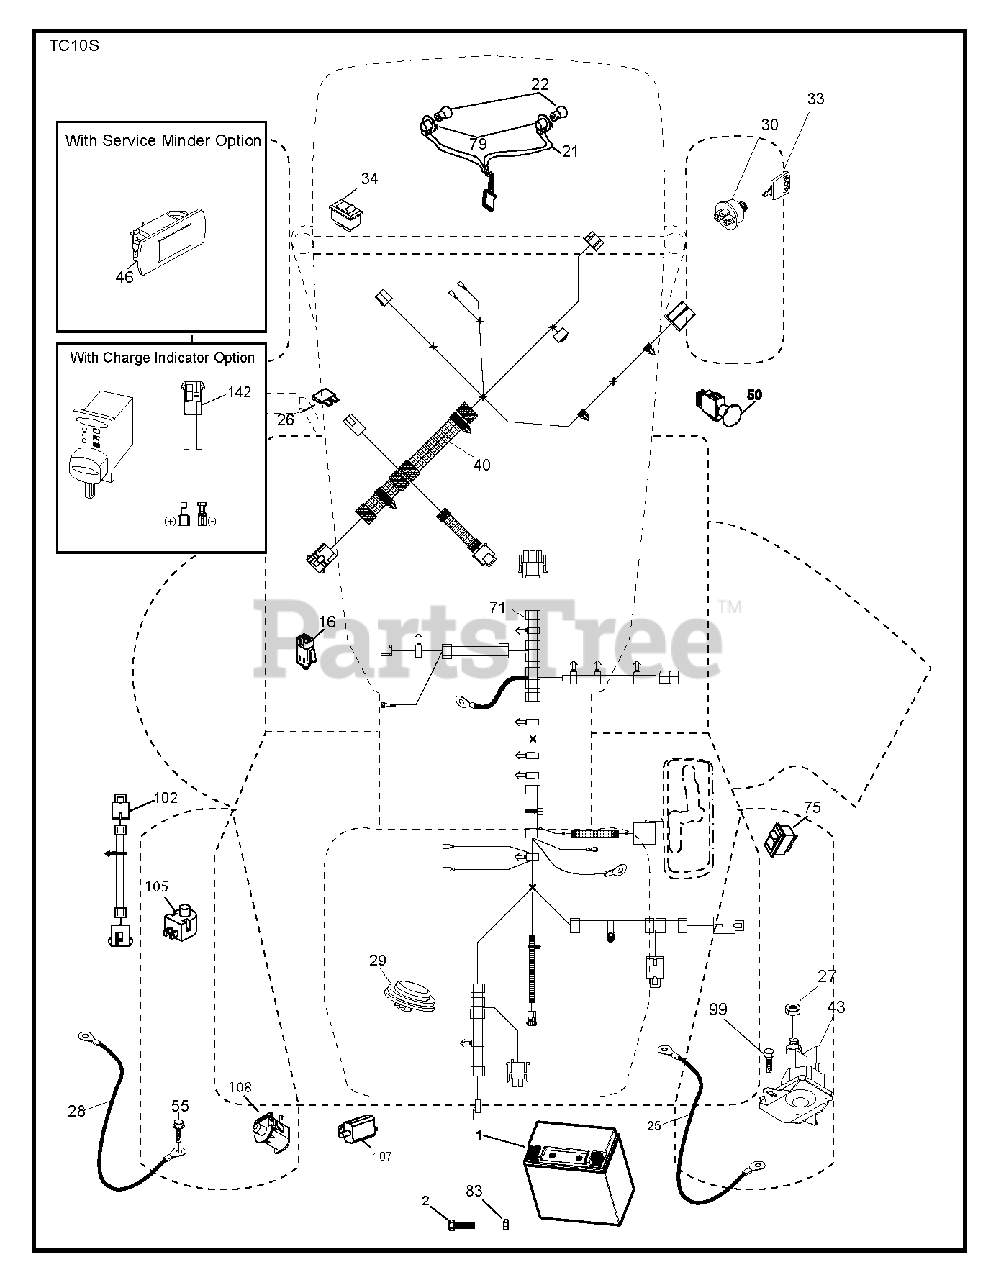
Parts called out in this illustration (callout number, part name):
16	SWITCH INTERLOOK PUSH-IN
21	HARNESS.LIGHT W/4152J BULBS
22	LIGHTBULB
26	FUSE 20AMP
27	NUT
29	SWITCH.SEAT.DELTA.OPC.
30	SWITCH.IGN.DELTA.W.LGH.ROS
33	KEY.CHAIN.BLISTER.PACK.GEN.INT
34	SWITCH LT
43	SOLENOID.W/BRASS.PLUNG
46	GUAGE.SRVCMNDR.HRMTR.
50	PTO SWITCH
55	SCREW 5/16"
79	BULB HOLDER ASM.
99	SCREW
105	REVERSE SWITCH
108	SWITCH.SNAPMOUNT.NC
